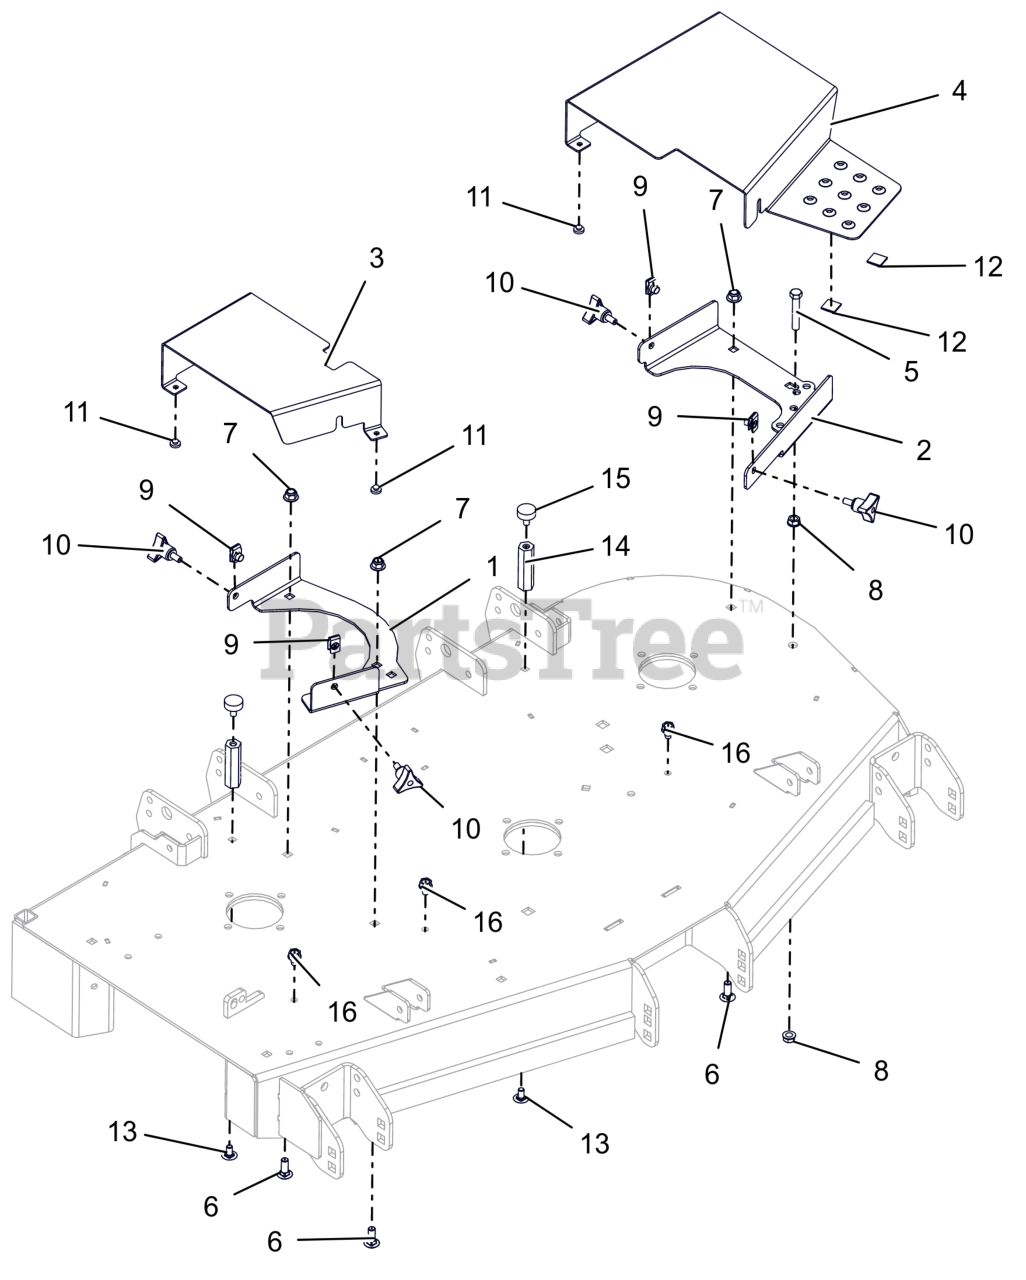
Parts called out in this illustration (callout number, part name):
1	BRKT, RH BELT GUARD MTG - RED
2	BRKT, LH BELT GUARD MTG - RED
3	PT148-152 DECK RH BELT GRD-RED
4	PT100 DECK LH BELT GUARD - RED
5	BLT,HEX .38-16X2.25 G5 ZCC
6	BLT, RHSN .38-16X1.00 G5 ZCC
7	NUT,NYL-FLG .38-16 GF ZCC
8	NUT, SPNLK-FLG .38-16 G5 ZCC
9	NUT-CLIP RETAINER 5/16-18X.56
10	KNOB,WING STUD 5/16-18 X .75
11	BUMPER GROMMET
13	BLT, RHSSN .31-18X.625 G5 ZCC
14	NUT, COUPLING .31-18 2.75 LG
15	BUMPER, RUBBER
16	SCR,TAP .375-16X.50 HWH TR ZCC
